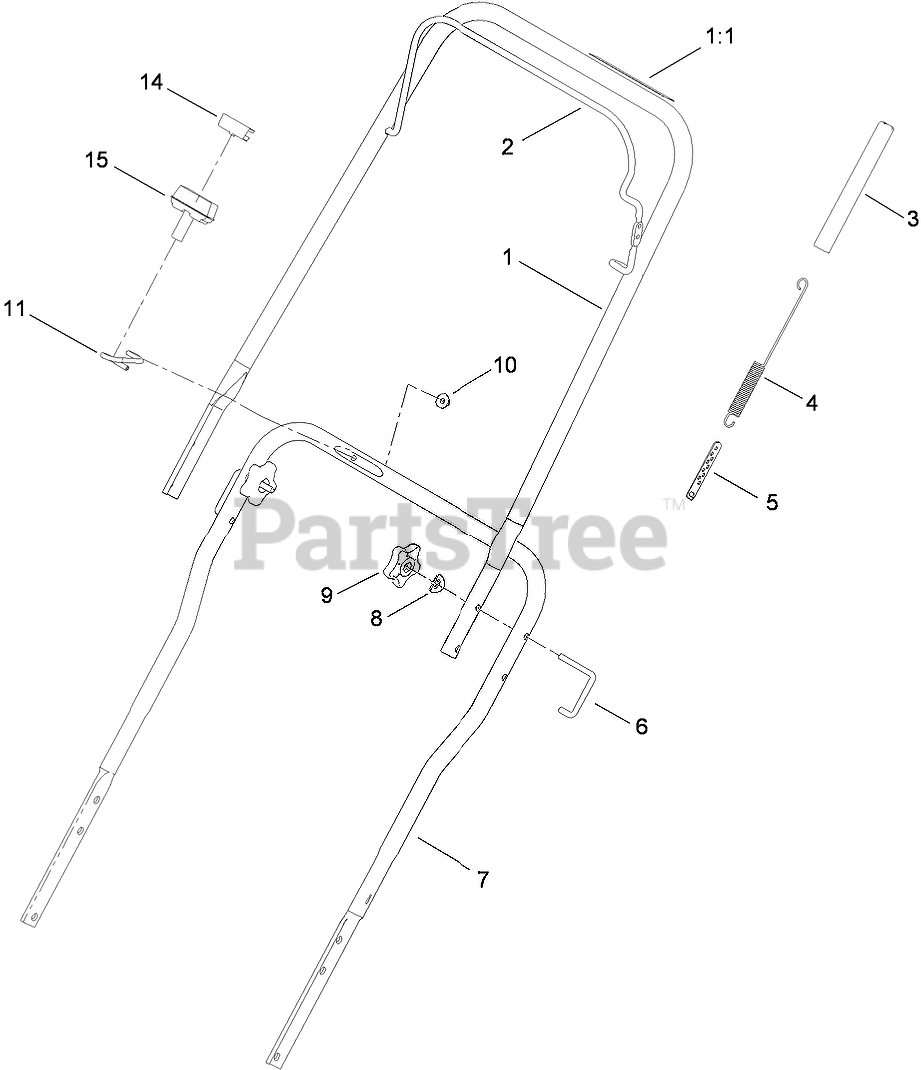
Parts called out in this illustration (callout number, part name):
1	UPPER HANDLE ASM
1:1	DECAL-DRIVE, ROTOR
2	BAIL-CLUTCH
3	COVER-SPRING
4	SPRING-EXTENSION, CLUTCH
5	ADJUSTER-CABLE, CLUTCH
6	LOCK-HANDLE
7	HANDLE-LOWER
8	WASHER
9	KNOB-HANDLE
10	NUT-HEX FLG
11	GUIDE-ROPE
14	CLIP-STARTER
15	HANDLE-START
